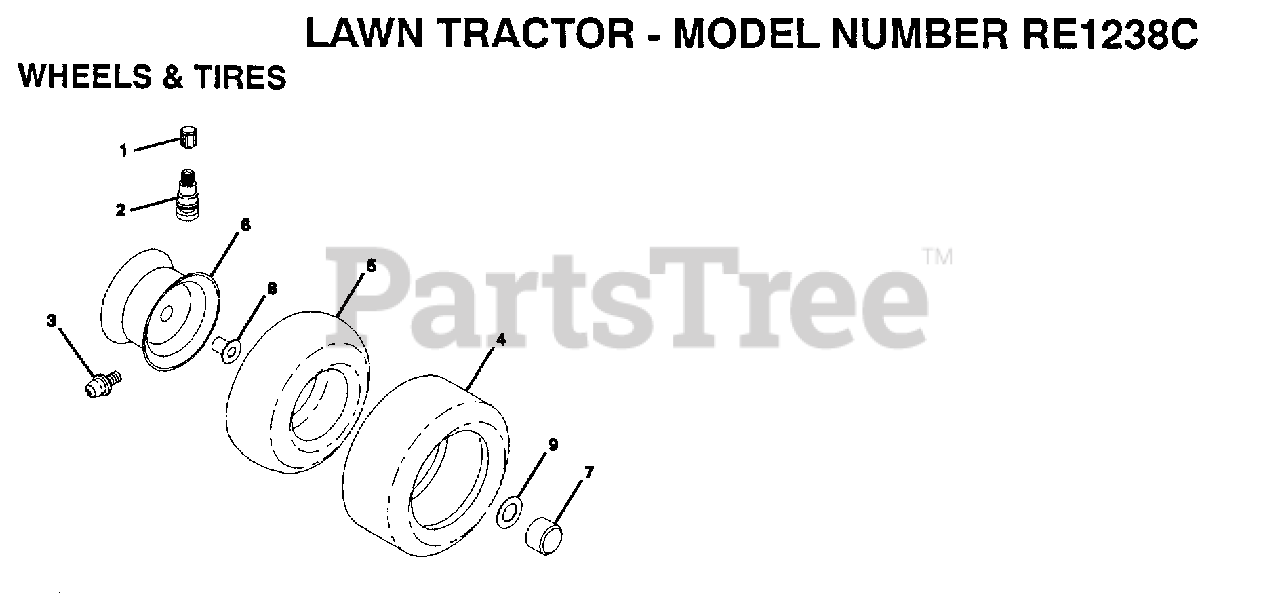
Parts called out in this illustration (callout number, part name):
1	VALVE CAP
2	VALVE STEM LT
3	FITTING LT
5	TUBE.18X9.5-8
5A	TUBE.5.3/4.5/6
7	HUB CAP
8	"FLANGE, BEARING"
9	WASHER
